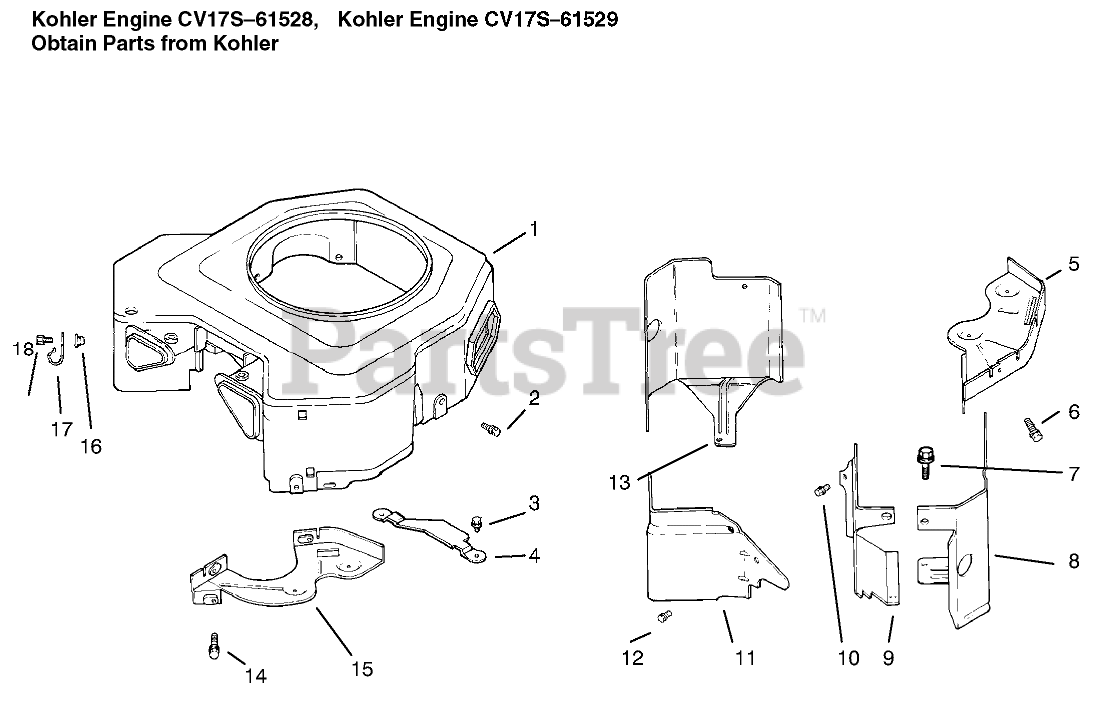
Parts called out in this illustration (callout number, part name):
1	Blower Housing ASM
3	Screw
4	Guard-Flywheel
5	Plate-Backing #2 Side
7	Screw
8	Baffle-Cylinder, #2
9	Baffle-Valley #1 Side
10	Screw
11	Baffle-Valley #2 Side
13	Baffle-Cyl. #1 Side
14	Screw
15	Plate-Backing #1
16	Nut
17	Clamp
18	Screw
